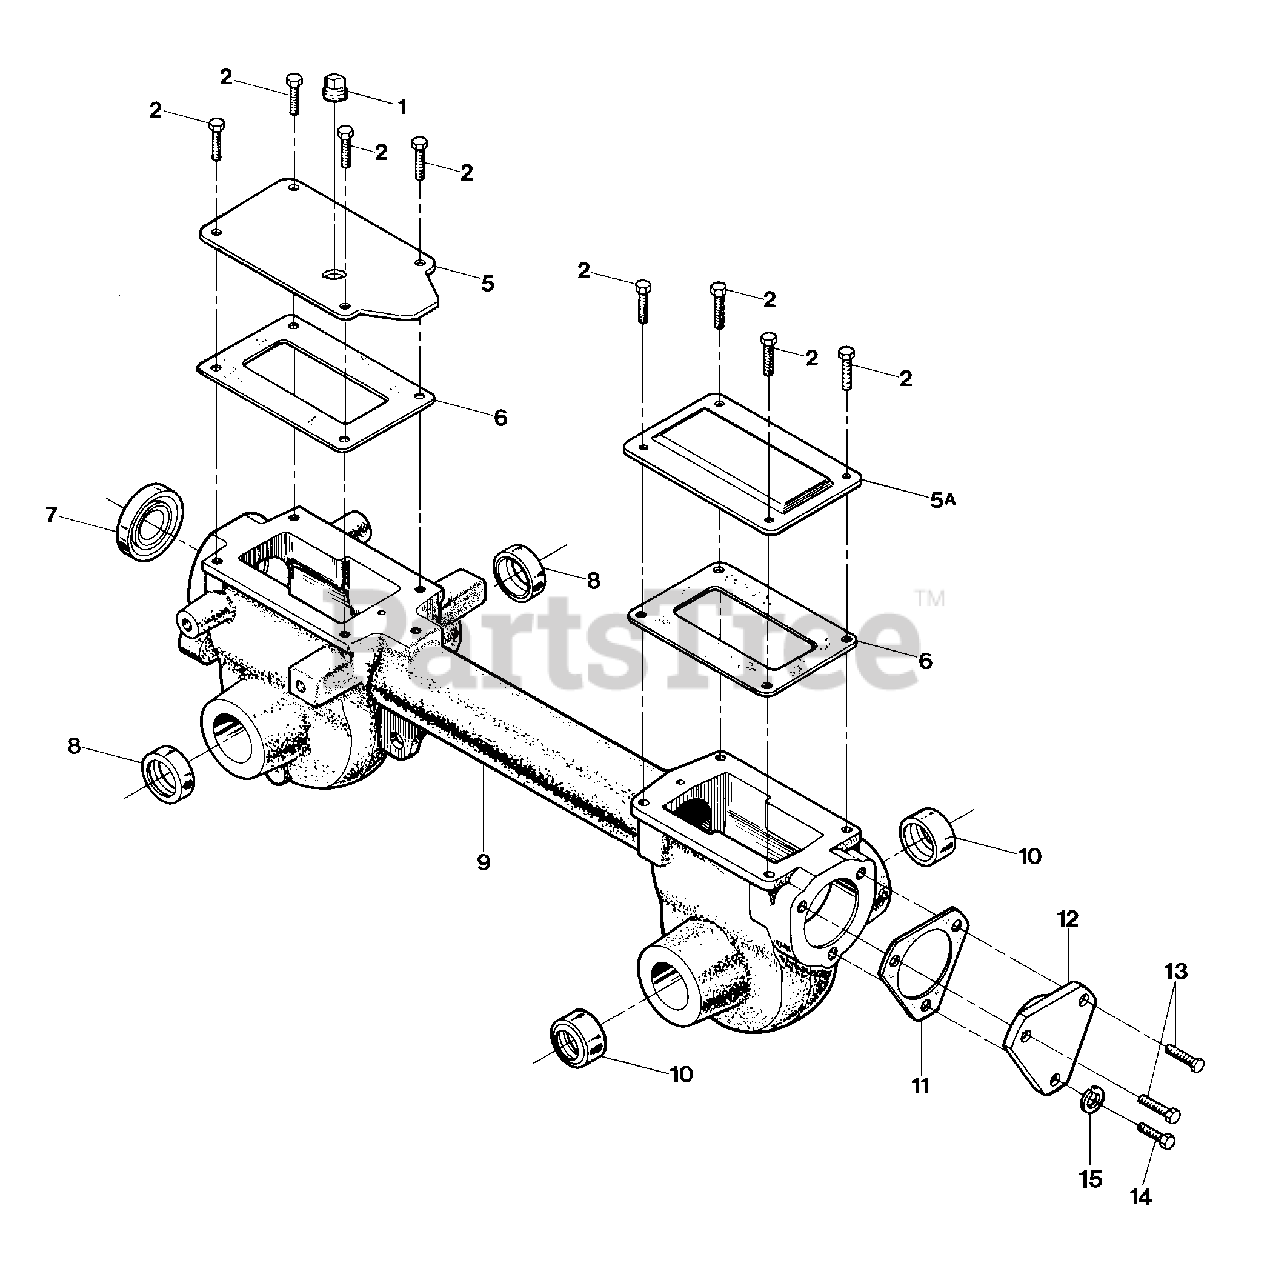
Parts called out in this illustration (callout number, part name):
1	Plug, Transmission Oil Fill
2	Flange Screw, Grade 5, 5/16-18 x 5/8
5	Front Cover, Trans. Housing
5A	Rear Cover, Trans. Housing
6	Gasket, Trans. Housing Cover (Front and Rear)
7	Oil Seal, Drive Shaft
8	Oil Seal, Wheel Shaft
9	Transmission Case, Rear Housing and Tube Assembly
10	Oil Seal, Tine Shaft
11	Gasket, Bearing Cap (.010 thick)
12	Cap, Rear Bearing
13	Flange Screw, 5/16-18 x 1
14	Flange Screw, 5/16-18 x 3/4
15	Lockwasher, 5/16
